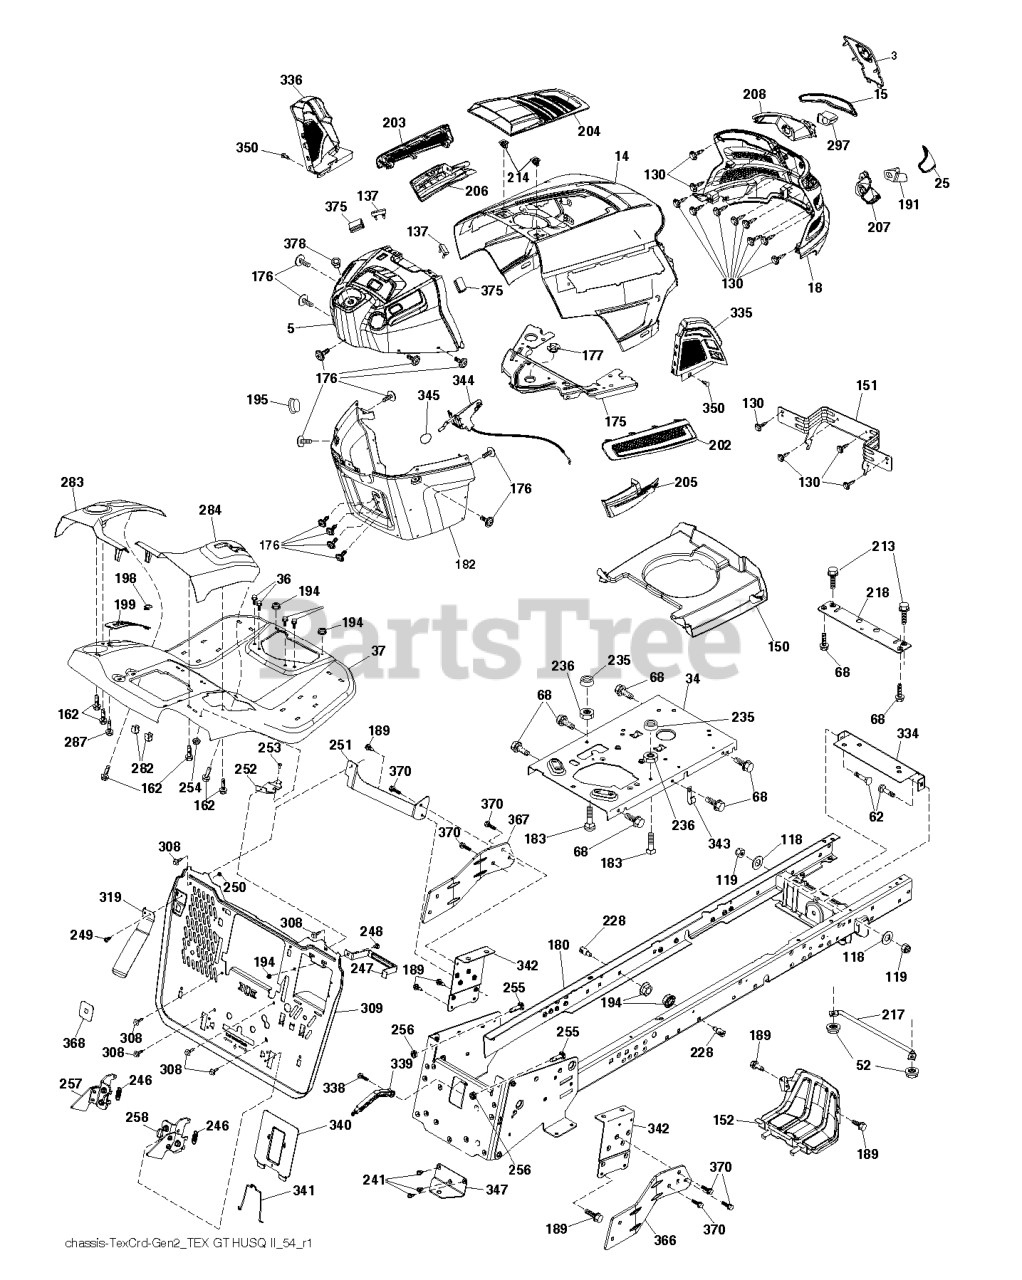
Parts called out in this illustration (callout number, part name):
3	APPLIQUE.SUBASM.GT.HUSQ.II
5	DASHBOARD.TEX.GT2.UPPER.S.PTO
14	HOOD.ASM.HUSQVARNA.GT.TEX.ORAN
15	LENS.HEADLIGHT.LH.GTII.2011
18	GRILLE SUBASM.GT.II.LOW.HDLGHT
25	LENS.HEADLIGHT.RH.GTII.2011
34	PLATE.ENGINE.10GA.CRD.GENII
36	SCREW 5/16"
37	FENDER.TEX.SRD.CRD.BASE
52	LOCKNUT
62	BOLT D
68	SCR 5/16-18 X 1/2 SELFTAP ZN
118	WASHER
130	SCREW.#10 X 0.750.BOS
137	BUMPER DASH
150	AIR DUCT.GTV2(1.66"RING HEIGHT
151	BRACKET.PIVOT.HOOD.GT.HUSQ.II
152	SHIELD.BROWNING.PNT.GT.V2
162	SCREW.HI-LO.CONSOLE
175	PLATE.PNT.CROSSMEMBER.HUSQ/PRE
176	SCREW.#10-24X5/8.RN.QU
177	BUSHING STEERING
180	CHASSIS WELDMENT.CRD2.BKP_BLTS
182	DASH DASH LOWER
183	BOLT.5/16-18X1-1/4 FULL THD
189	SCREW
191	INSERT.REFLECTIVE.RH.HUSQ.GTII
194	NUT LOCK HEX FLANGE 5/16-18
195	PLUG.HOLE.DASH.LOWER.12V.BLK
198	INDICATOR.DECK.LIFT.RED
199	PLATE DECK LIFT
202	VENT.SIDE.RH.GT.HUSQ.II.
203	VENT.SIDE.LH.GT.HUSQ.II.498
204	VENT.TOP.HUSQ.GT2
205	SIDE.TRIM.RH.GT.HUSQ.II
206	SIDE.TRIM.LH.GT.HUSQ.II.GRAY
207	HEADLIGHT.CUP.BEZEL.HUS.GT2.RH
208	HEADLIGHT.CUP.BEZEL.HUS.GT2.LH
213	HCS 5/16C X 3/4
214	CLIP.RETAINER.TINNER.
217	ROD.PIVOT.HOOD
218	X-PIECE.HOOD.STOP.NON/
228	STUD.FASTNER.W/ANTI-ROTATE
235	SPACER FENDER
236	NUT.CENTERLOCK.5/16-
241	SCREW 5/16-18X1
246	SPRING.LTCH.BGR.GEN2.5.CRD.TEX
247	STRAP.BATTERY.TCRD.GEN2.5X431
248	BOLT.CARR.5/16-18X1/2
249	SCREW.BUTTONHD.10-24X1/2.(2 2)
250	NUT 10-24 NYLOC
251	BRACKET.PNT.LH.SUPP.BKPLT.EDIP
252	BRACKET.PNT.RH.SUPP.BKPLT.EDIP
253	1/4-20X3/4 CARR BLT
254	NUT T
255	BOLT CROSS DRILLED CUP HEAD SQ
256	NUT.HEX.3/8-16
257	LATCH.ASM.BGR.LH.GEN2.5.STMPD
258	LATCH.ASM.BGR.RH.GEN2.5.STMPD
282	CLIP.RETAINER.CONSOLE.LT.HUSQ
283	CONSOLE.DECKLIFT.CRDII.498
284	CONSOLE.PEDAL.HYDRO
287	SCREW 1/4X20
297	INSERT.REFLECTIVE.LH.HUSQ.GTII
308	BOLT.5/16-18UNCX3/4 W/SEMS.BLK
309	BACKPLATE.TEXCRD2.5.BAGGER.479
319	LEVER.BAG.CRDII.ANTIROTATION
334	BRACKET.ENGINE
335	COVER.LOWER.DASH.RH.BLACK
336	COVER-LH.LOWER.DASH.GT2.BLACK
338	BOLT BOLT SHOULDER
339	LEVER LEVER BAGGER
340	BATTERY.DOOR.TCRD.GEN2.5.MS479
341	LATCH.BATTERY.DOOR.TCRD
342	SUPPORT.PNT.FENDER.CRD.TEX
343	CLIP CLIP
344	CONTROL.EZ.MULCH.TEX/CRD
345	RP KNOB.OVAL.TAPERED.3/8-16BLK
347	HITCH HITCH TOW TEX CRD GEN 2
350	CLIP.X-MAS.TREE
366	BRACKET.RH.FRONT.BAGGER.BLACK
367	BRACKET.LH.FRONT.BAGGER.BLACK
368	.WITCH.FULL BAGGER.INDICATOR
370	SCREW 3/8-16X1
375	BUMPER CLIP-ON. DASH 1"
378	BUSHING FLANGE; PLASTIC
